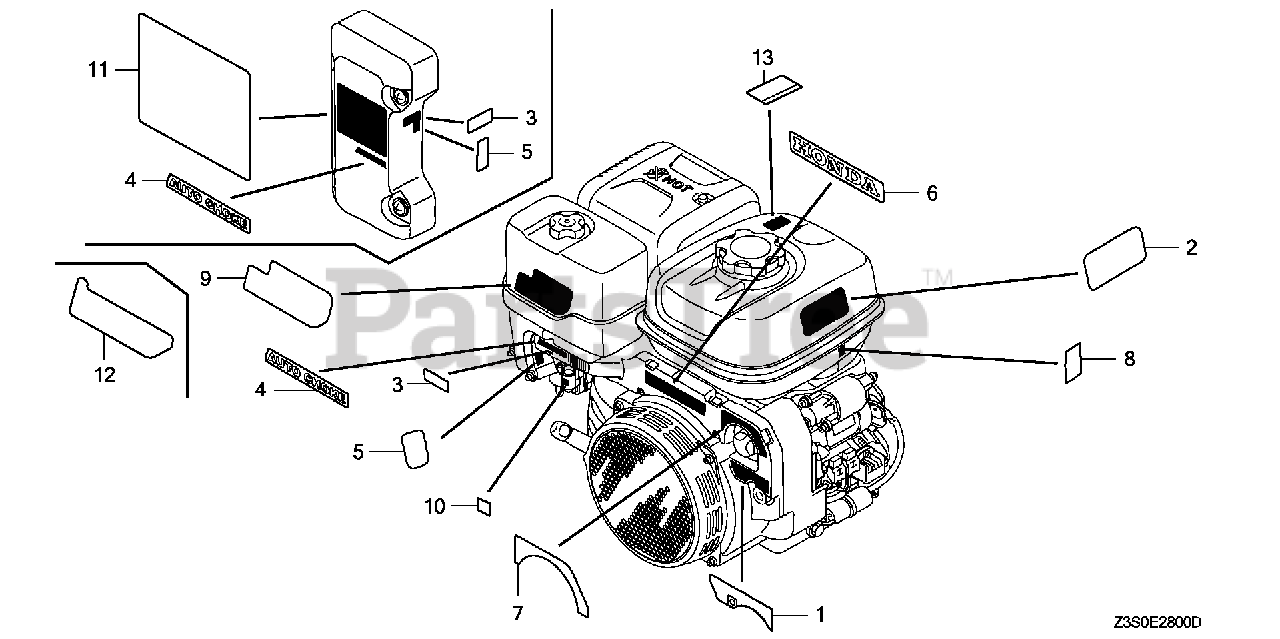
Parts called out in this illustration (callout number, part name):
1	MARK, ENGINE SWITCH
2	MARK, OPERATOR CAUTION (ENGLISH)(MADE IN JAPAN)
2	MARK, OPERATOR CAUTION (PICTOGRAPH)(MADE IN JAPAN)
2	MARK, OPERATOR CAUTION (PICTOGRAPH)
3	MARK, CHOKE
6	MARK, HONDA
8	MARK, OIL CAUTION
9	MARK, SALES POINT
12	MARK, SALES POINT
